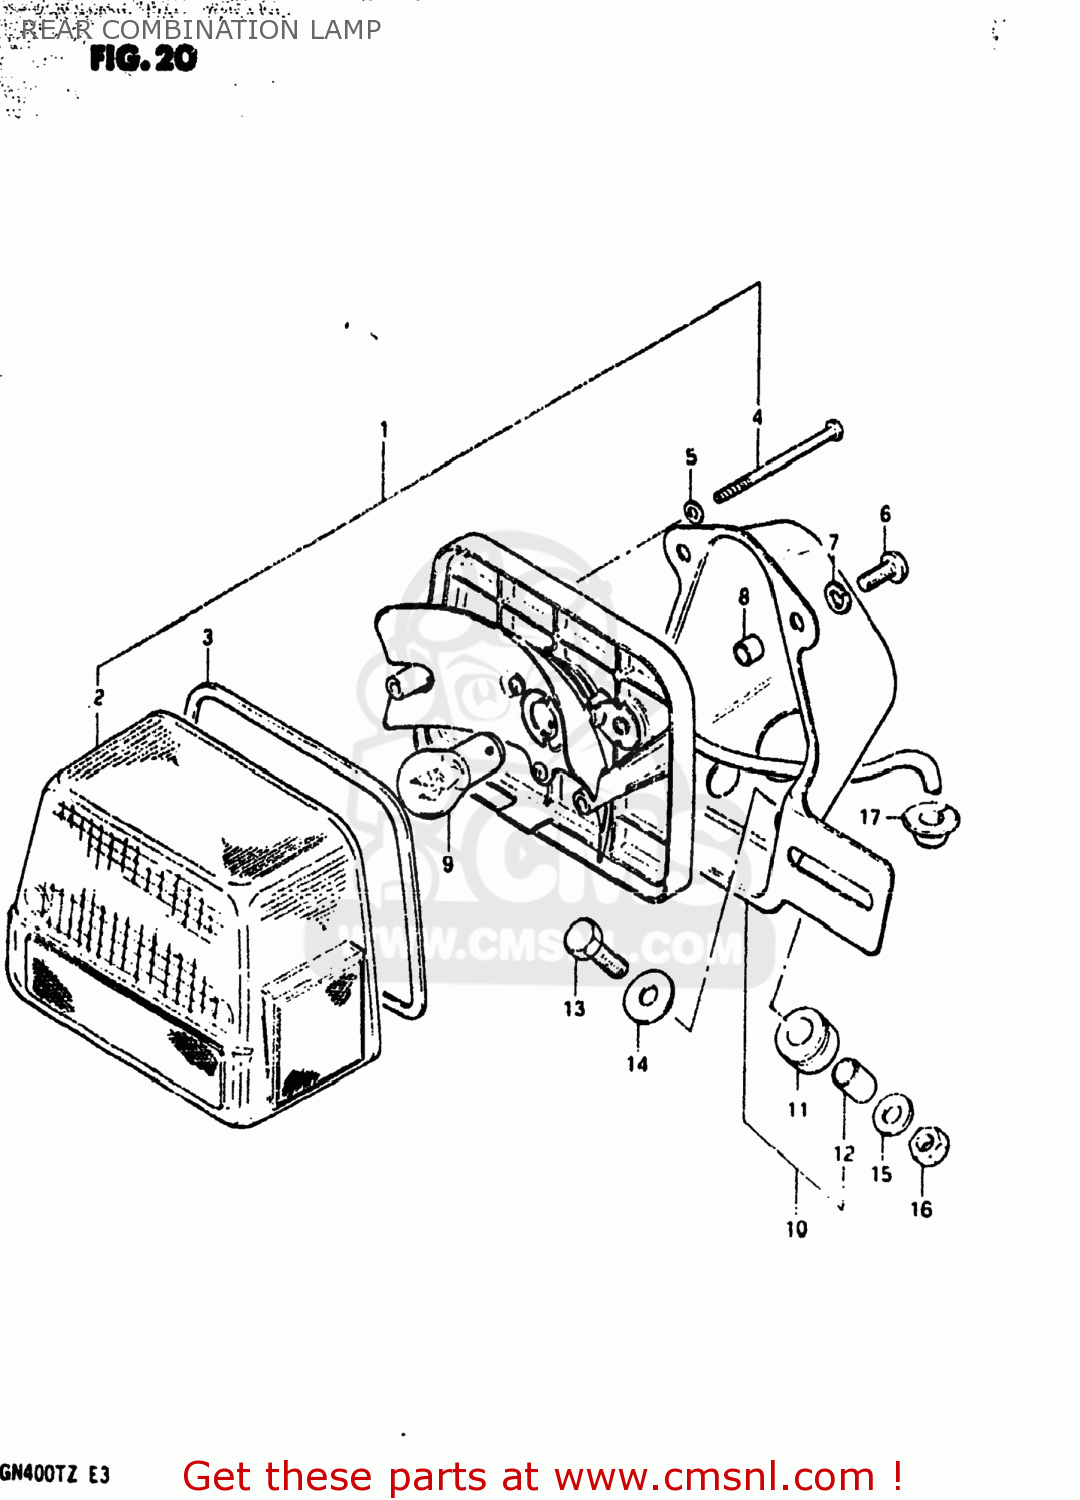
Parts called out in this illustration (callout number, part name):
1	LAMP UNIT,RR COMBNATION
2	LENS
3	GASKET (NAS)
4	SCREW
5	GASKET (NAS)
6	SCREW
7	LOCK WASHER
8	SPACER
9	BULB(6V32/3CP,STANLEY)
10	BRACKET UNIT,TAIL LAMP
11	CUSHION
12	SPACER
13	BOLT
14	WASHER (6.5X20X1.2)
15	WASHER
16	NUT
17	GROMMET
